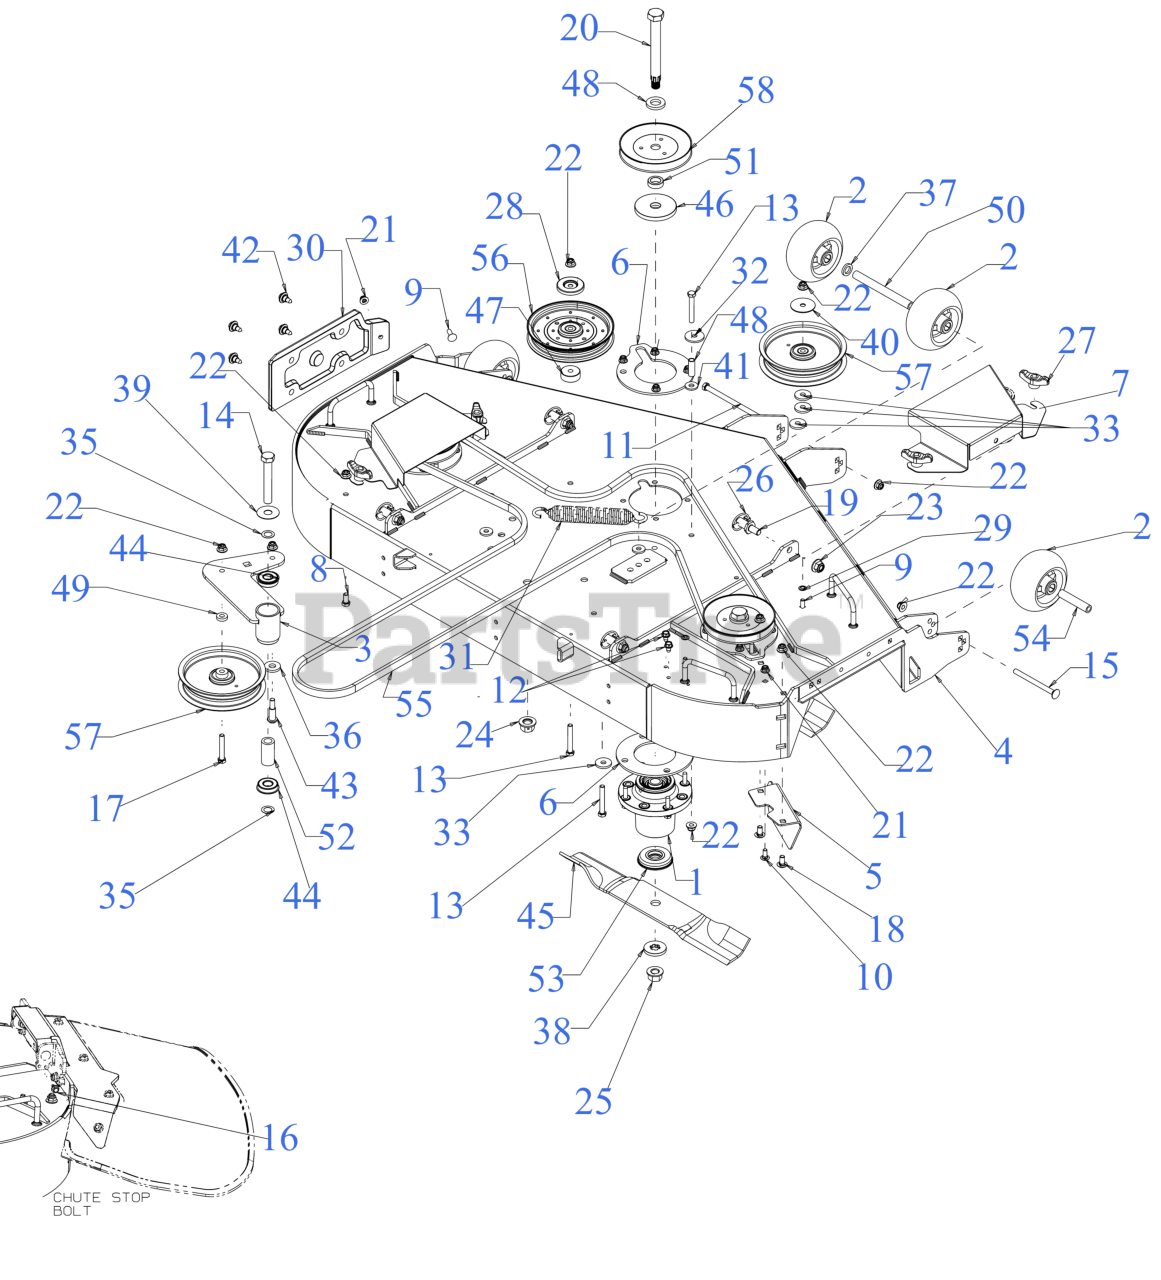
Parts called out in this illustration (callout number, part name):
1	SPINDLE ASSEMBLY
2	5" DIA DECK WHEEL COMPLETE
3	IDLER ARM ASSEMBLY
4	54" FAB DECK ASSEMBLY
8	HEX SCREW 3/8-16 x .75
9	CARRIAGE BOLT 5/16-18 x 1.00
10	CARRIAGE BOLT 5/16-18 x .75
11	SCREW 3/8-16 x 7.25 GR5
12	SCREW 5/16-18 x .500
13	HEX SCREW-3/8-16X2.5 GR5
14	SCREW 5/8-18 x 4 GR5
15	CARRIAGE BOLT 3/8-16 x 4.25 GR5
16	SCREW 1/4-20X.625
17	SCREW 3/8-16 x 2.25 GR5
18	CARRIAGE BOLT 3/8-16 x .75
20	SPINDLE SHAFT
21	FLANGE LOCK NUT 5/16-18
25	FLANGE NUT - 5/8-18 GDE 8
26	LYNCH PIN .1875
27	WING KNOB 5/16-18
28	PULLEY CAP
30	DECK SKID PLATE (LH)
31	SPRING 1.25" DIA x 8.5" LONG
32	FLAT WASHER .390x1.500x.134
33	FLAT WASHER
34	FLAT WASHER .385 x 1.00 x .135
35	FLAT WASHER
36	FLAT WASHER .531 x 1.25 x .181
37	FLAT WASHER .632X1.00X.16
38	FLAT WASHER - SPECIAL
39	THRUST WASHER .635x1.750x0.055
40	HUB CAP WASHER .406 x 1.92 x .060
41	FLAT WASHER .406ID X1.0 OD
42	SHOULDER SCREW .43X.29X5/16-18 TT
43	SHOULDER SCREW .50X.925
44	BALL BEARING W/RET
45	19" BLADE (HI LIFT)
45	Cub Cadet 54" HI LIFT BLADE SET
45	LOW-LIFT 19"BLADE (54"DECK)
45	BLADE- HI LIFT 19.0 XTREME
45	19" XTREME BLADE
46	DECK SPINDLE SPACER
47	SPACER - .385 ID x 1.500DX .585 L
50	WHEEL SPACER
51	SPACER (.792 x 1.20 x .380)
52	SPACER 0.63 x 1.00 x 2.01
53	SPACER 0.790 x 2.75 x 0.486
54	WHEEL SPACER .38ID x 3.04LG
55	DECK BELT B SEC x 154
56	IDLER PULLEY
57	IDLER PULLEY (6.00" DIA)
58	SPINDLE PULLEY (5.625")
